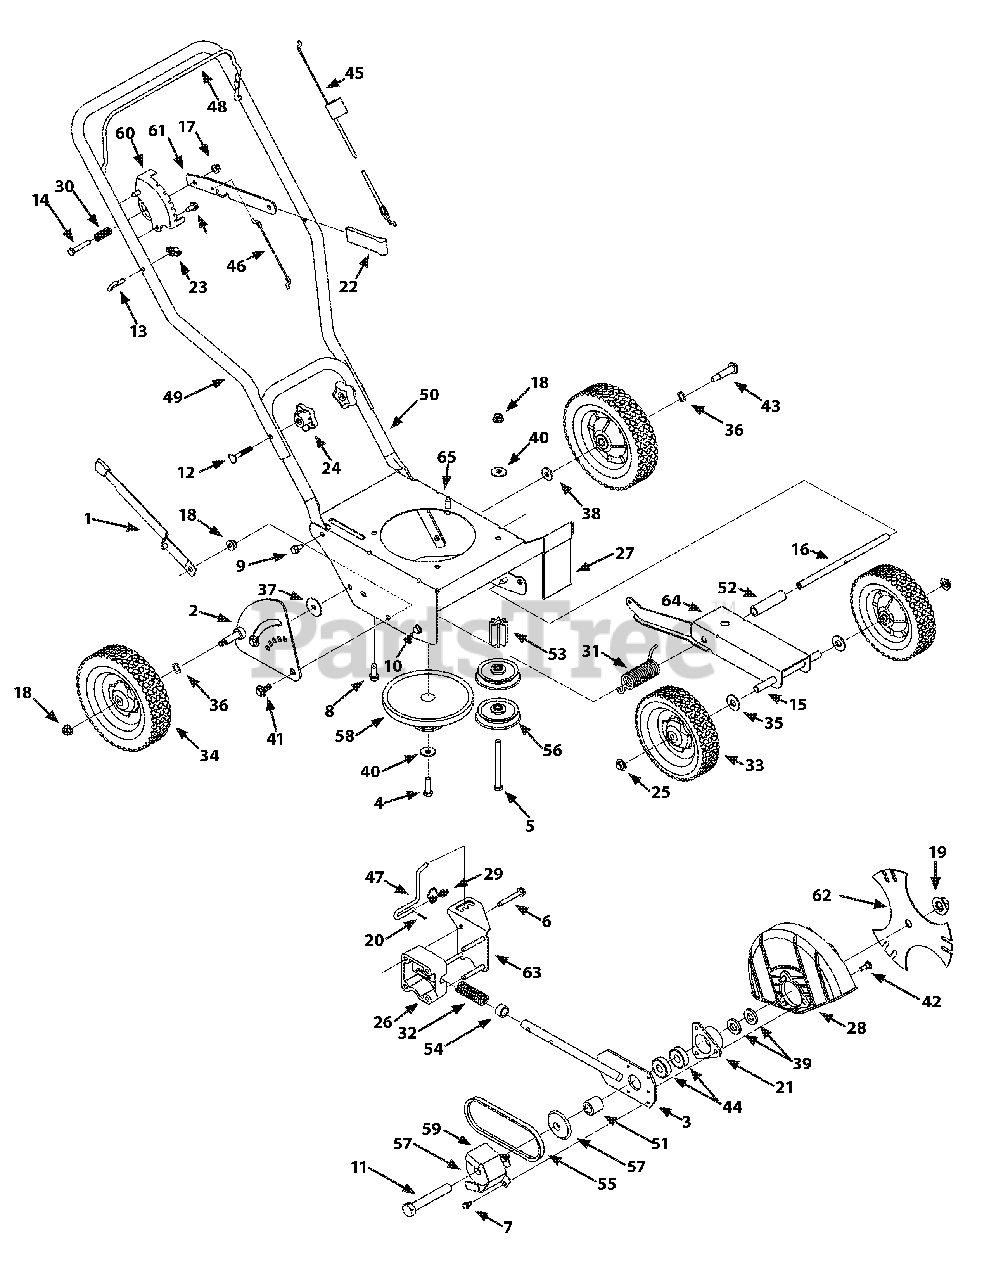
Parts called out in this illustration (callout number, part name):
1	Curb Height Adjustment Lever
2	Curb Height Adjuster Plate
3	Blade Plate Assembly
4	Screw 3/8-24 x 1.25
5	Screw 3/8-16 x 4.00
6	Hex Screw, 5/16-18
7	Self-tapping Screw, 1/4-20
8	Screw, 3/8-16
9	Hex Screw, 5/16-12
10	Hex Screw 3/8-16 x .625
11	Hex Screw, 5/8-18 x 4.0
12	Carriage Bolt, 5/16-18
13	Rope Guide (Eye Bolt)
14	Hex Screw, 5/16-18
15	Axle Shaft .50x6.65
16	Frame Spacer .50x9.25
17	Lock Flange Nut, 5/16-18
18	Flange Nut 3/8-16
19	Flange Nut, 5/8-18
20	Clevis Pin 3/32 x .625
21	Bearing Cup
23	Wing Nut
24	Star Knob
25	Push Cap 1/2" rod
26	Bearing Block
27	Debris Guard
28	Blade Guard
29	Double Torsion Spring
30	Compression Spring
31	Torsion Spring
32	Compression Spring
33	Wheel 7 x 1.75 T-Tread
34	Wheel 8 x 1.75 T-Tread
35	Flat Washer 1/2 x 1.25 x .10
36	Wave Washer .531 x .781 x .013
37	Flat Washer, .385 x 1.5 x .075
38	Flat Washer .385 x 1.0 x .135 †
39	Flat Washer .635x1.24x.181
40	Bell Washer,.396 x 1.140
41	Shoulder Screw, 3/8-16
42	Shoulder Screw, .375 x .280 x 1/4-14
43	Shoulder Screw, .496 x 1.44 3/8-16
44	Bearing, .625 ID x 1.57 OD
45	Control Cable (Briggs & Stratton)
46	Wheel Adjustment Cable
47	Blade Adjustment Rod
48	Bail Handle
49	Upper Handle
50	Lower Handle
51	Spacer, .63 x 1.12 x 1.06
52	Spacer
53	Pulley Mount Spacer
54	Spacer, .64 x.88 x .50
56	Flat Idler Pulley, 2.5 OD
57	Sheave
58	Combination Flywheel Pulley
59	Belt Guard
61	Depth Index Lever
62	Tri-Star Blade
63	Bracket Plate
64	Dual Wheel Bracket
65	Frame
